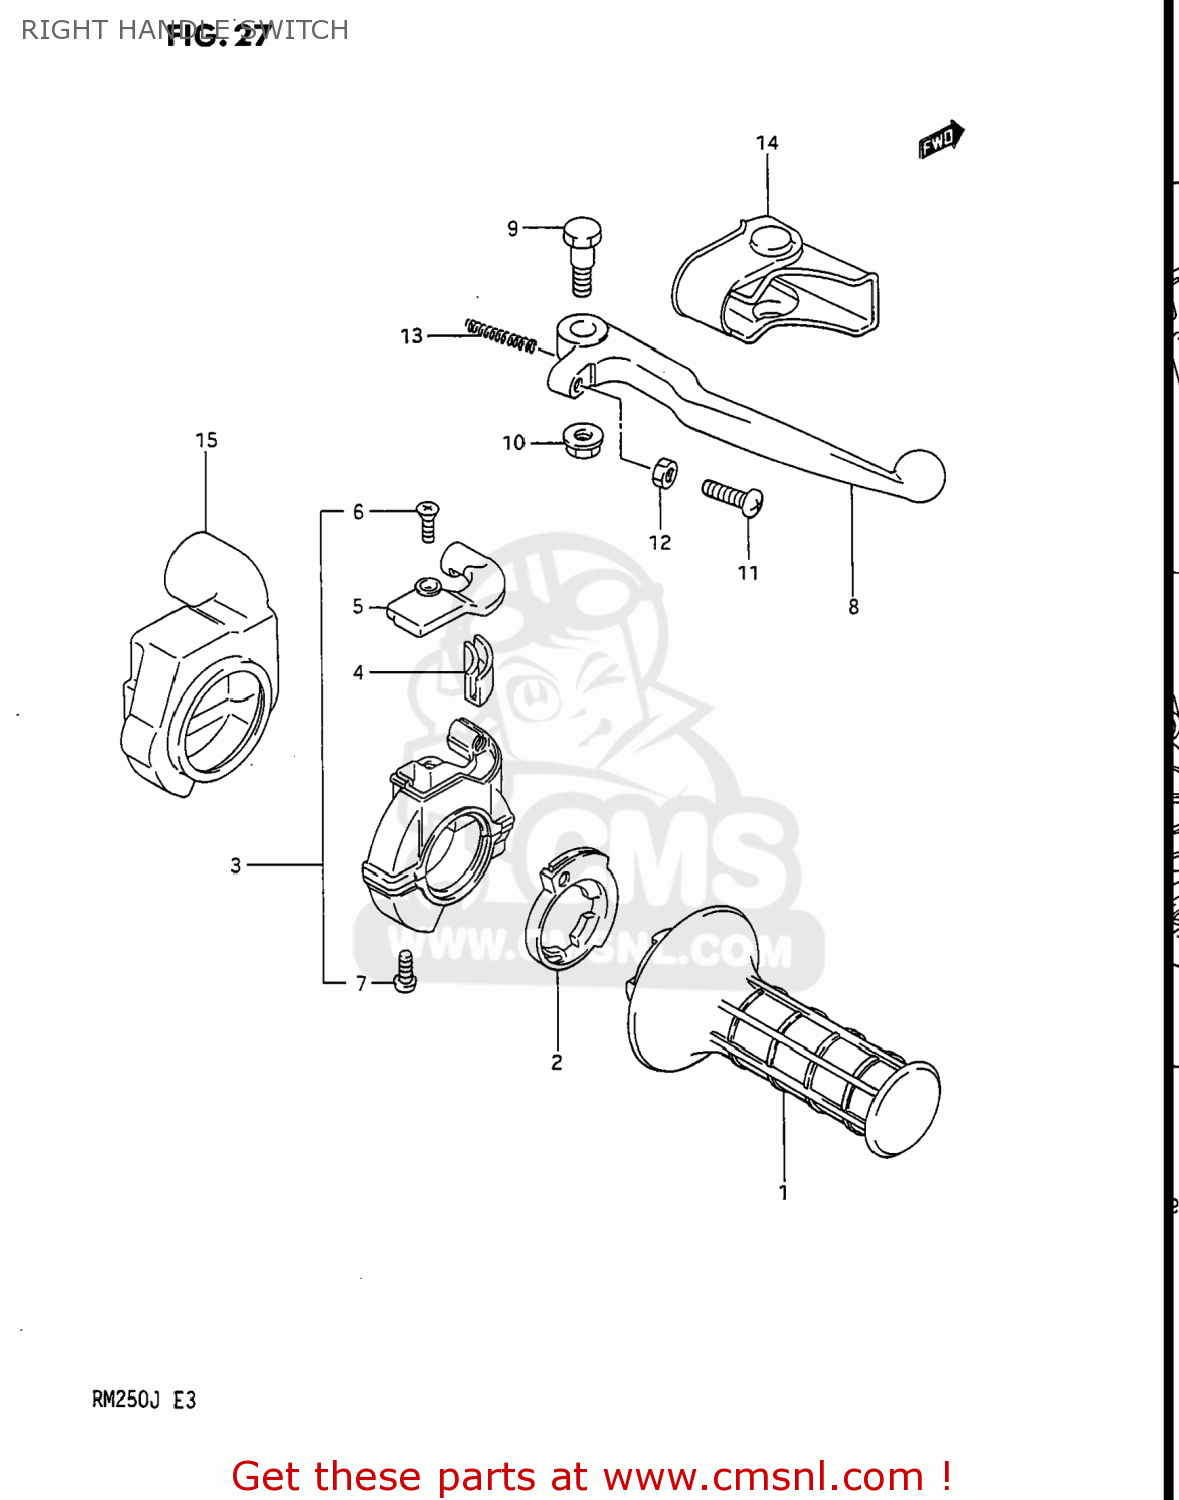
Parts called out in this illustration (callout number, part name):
1	GRIP,THROTTLE
2	ROTOR,THROTTLE GRIP
3	CASE ASSY,THROTTLE
4	GUIDE PIECE,THROTTLE
5	COVER,THROTTLE CASE
6	SCREW
7	SCREW
8	LEVER,BRAKE
9	BOLT,BRAKE LEVER
10	NUT,BRAKE LEVER
11	BOLT,ADJUST
12	NUT ,5MM
13	SPRING,RETURN
14	COVER,BRAKE LEVER
15	COVER,THROTTLE CASE
